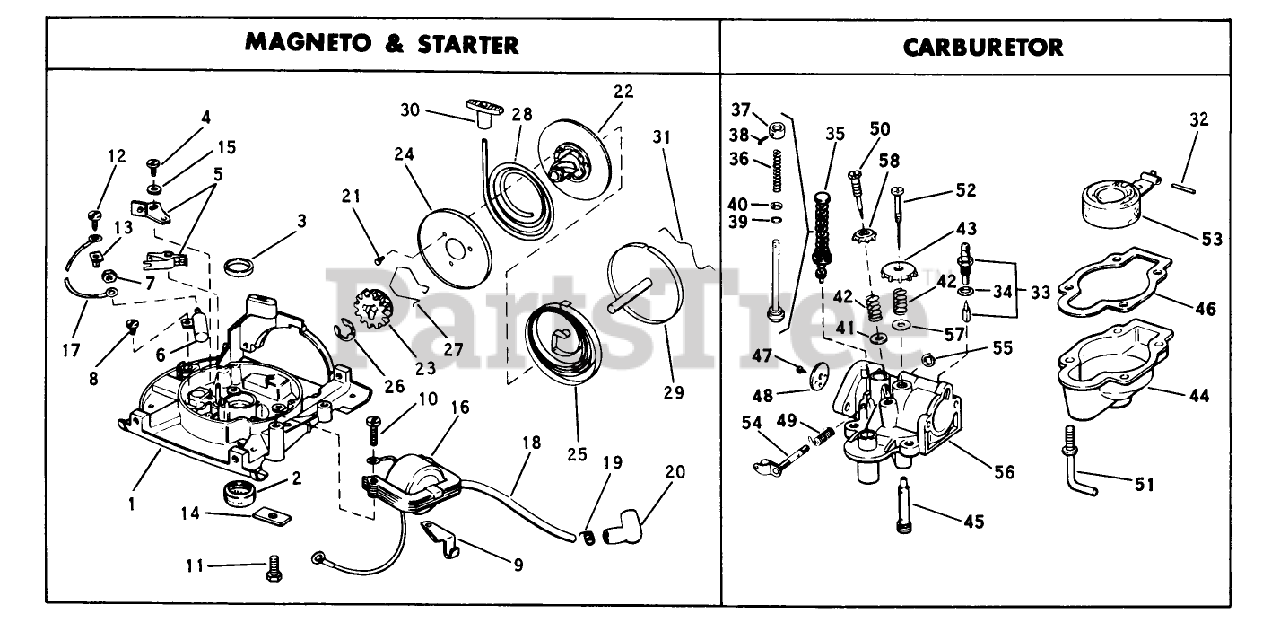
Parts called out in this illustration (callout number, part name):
2	BRG. & SEAL AY.
5	BREAKER AY. S
7	NUT S
8	Screw
9	Clip-High Tension Wire
11	SCREW S
13	NUT - CLIP
18	LEAD AY. S
20	Cover-Rubber
23	STARTER PINION S
25	SPRING S
27	STARTER SPRING S
31	SPRING S
35	PRIMER AY S
42	Spring-Ndl. Adj.
45	NOZZLE S
46	GASKET S
48	THROTTLE DISC S
52	NEEDLE AY. S
54	THROTTLE LEVER S
55	RING GRIP S
